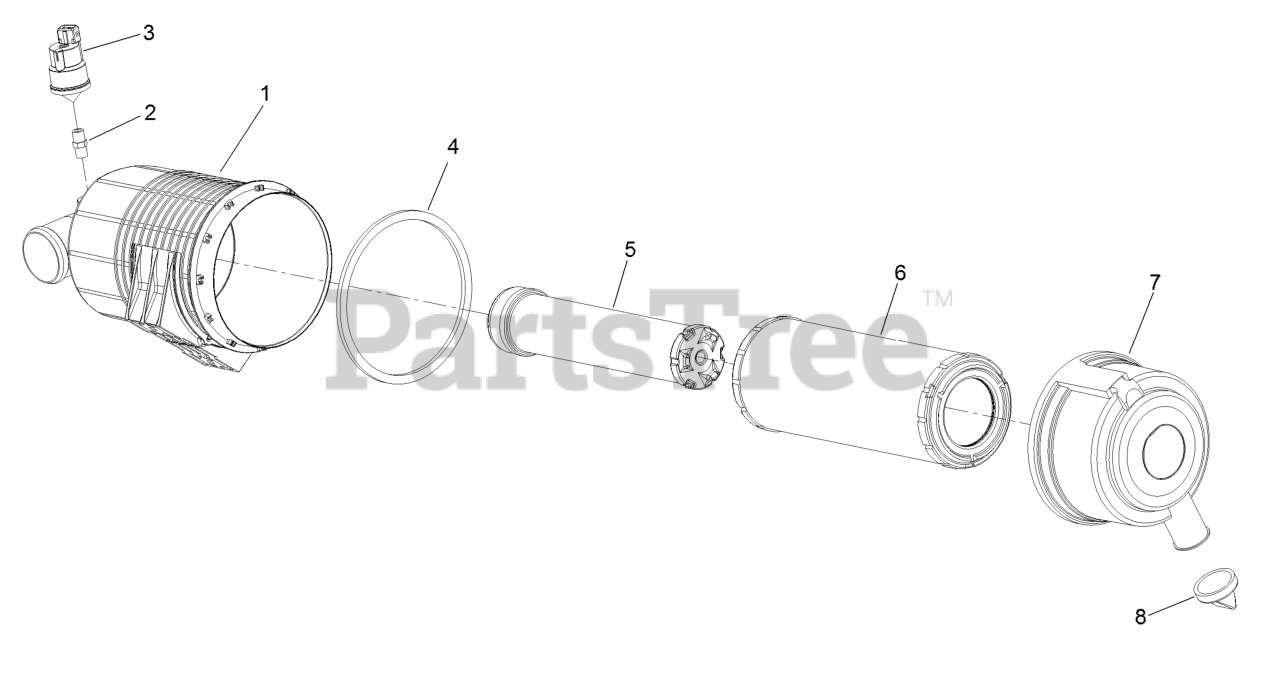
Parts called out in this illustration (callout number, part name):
1	Body-Cleaner, Air
2	Nipple-Pipe
3	Indicator-Mini
5	Element-Safety, 5 Inch
6	Filter-Air
8	Valve-Vacuator
